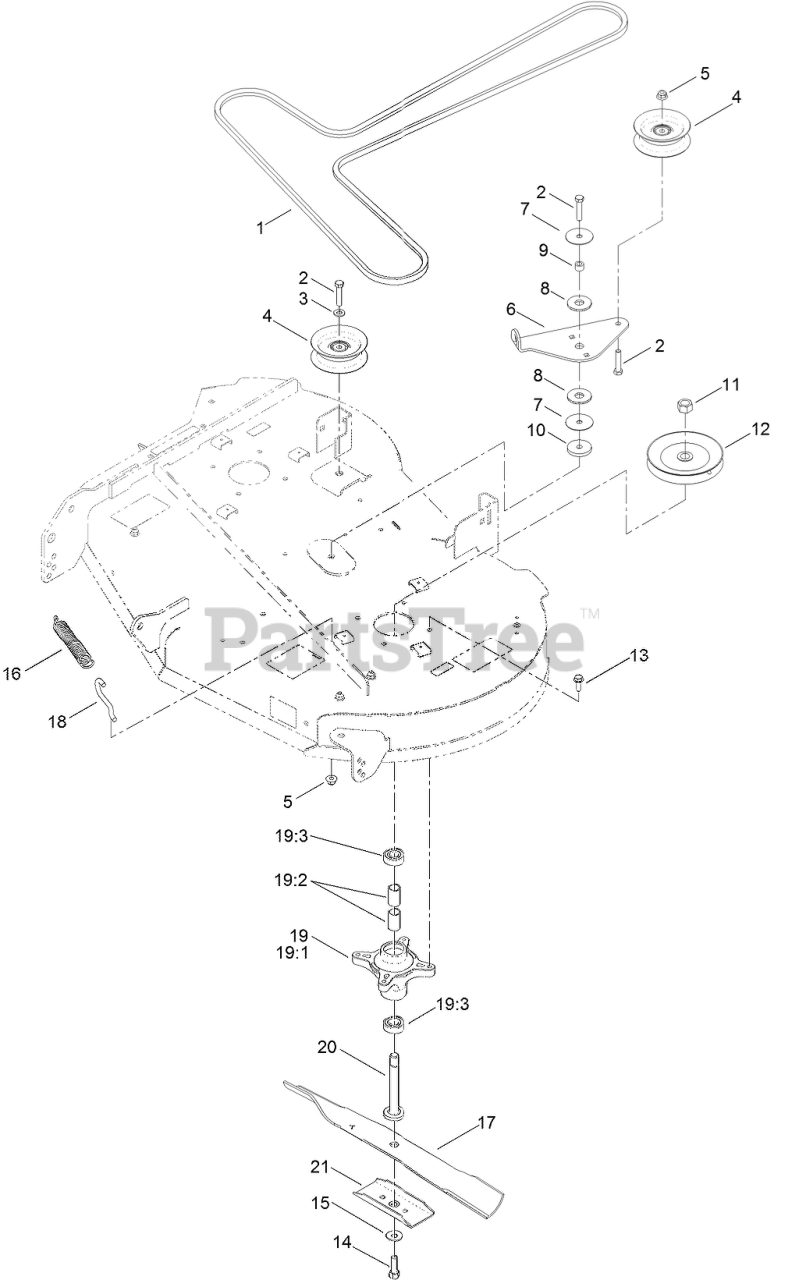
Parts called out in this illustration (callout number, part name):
1	V-BELT
2	SCREW-HH
3	WASHER-FLAT
4	PULLEY-IDLER, FLAT
5	NUT-HF, NI
6	ARM-IDLER
7	WASHER
8	WASHER-FRICTION, COMPOSITE
9	SPACER
10	WASHER-PLAIN
11	NUT-HEX
12	Pulley
13	SCREW-TAPTITE
14	SCREW-HH
15	WASHER-BELLEVILLE
16	SPRING-EXTENSION
18	HOOK-RETURN, SPRING
19	SPINDLE ASM
19:1	SPINDLE
19:2	SPACER
19:3	BEARING-BALL
20	SHAFT-SPINDLE
21	STIFFENER-BLADE
